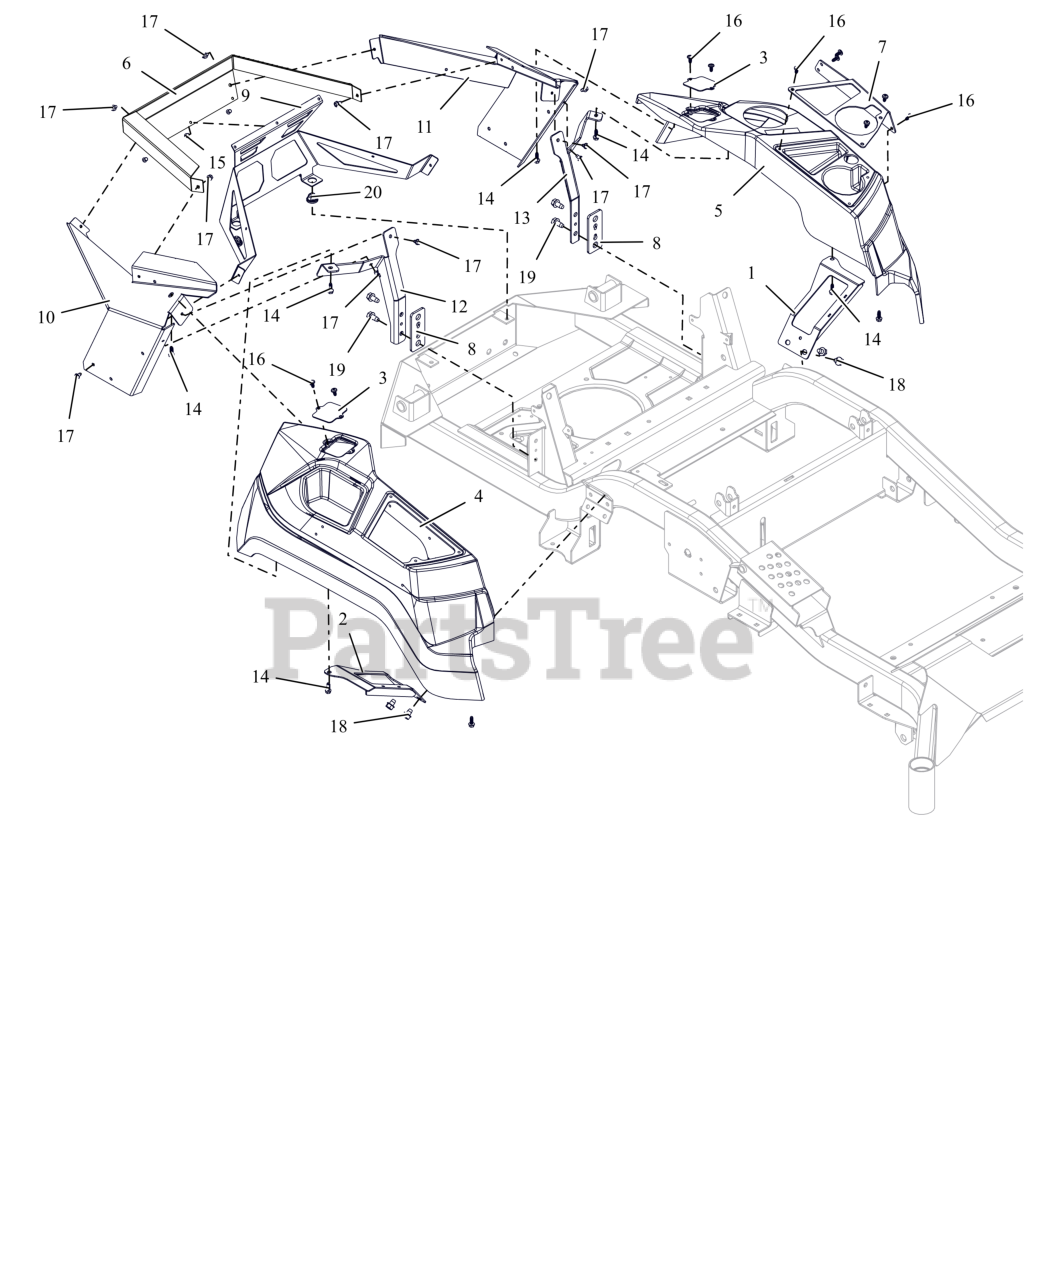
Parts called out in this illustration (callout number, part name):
1	WLDMT, LH FENDER MOUNT
2	WLDMT, RH FENDER MOUNT
3	PLATE, ROPS HOLE-HD
4	FENDER, RH APEX - 2017
5	FENDER, LH APEX
6	GUARD,ENGINE WRAP
7	PLATE, APEX CUP HOLDER COVER
8	PLATE, SPCR
9	GUARD, ENGINE
10	PANEL, RH REAR FENDER MOUNT
11	PANEL, LH REAR FENDER MOUNT
12	BRKT, RH FENDER MTG (ORANGE)
13	BRKT, LH FENDER MOUNT (ORANGE)
14	SCR, PLASTITE .25-10X.75 ZCC
15	RIVET, .1875 AL/AL .126-.250
16	SCR-PAN .25-15X.50 6L H/LZB500
17	SCR,TAP .25-20X.375 HWH TR ZCC
18	SCR,TAP .375-16X.50 HWH TR ZCC
19	SCR,TAP .375-16X.75 HWH TR ZCC
20	GROMMET, 10MM BOLLHOFF
